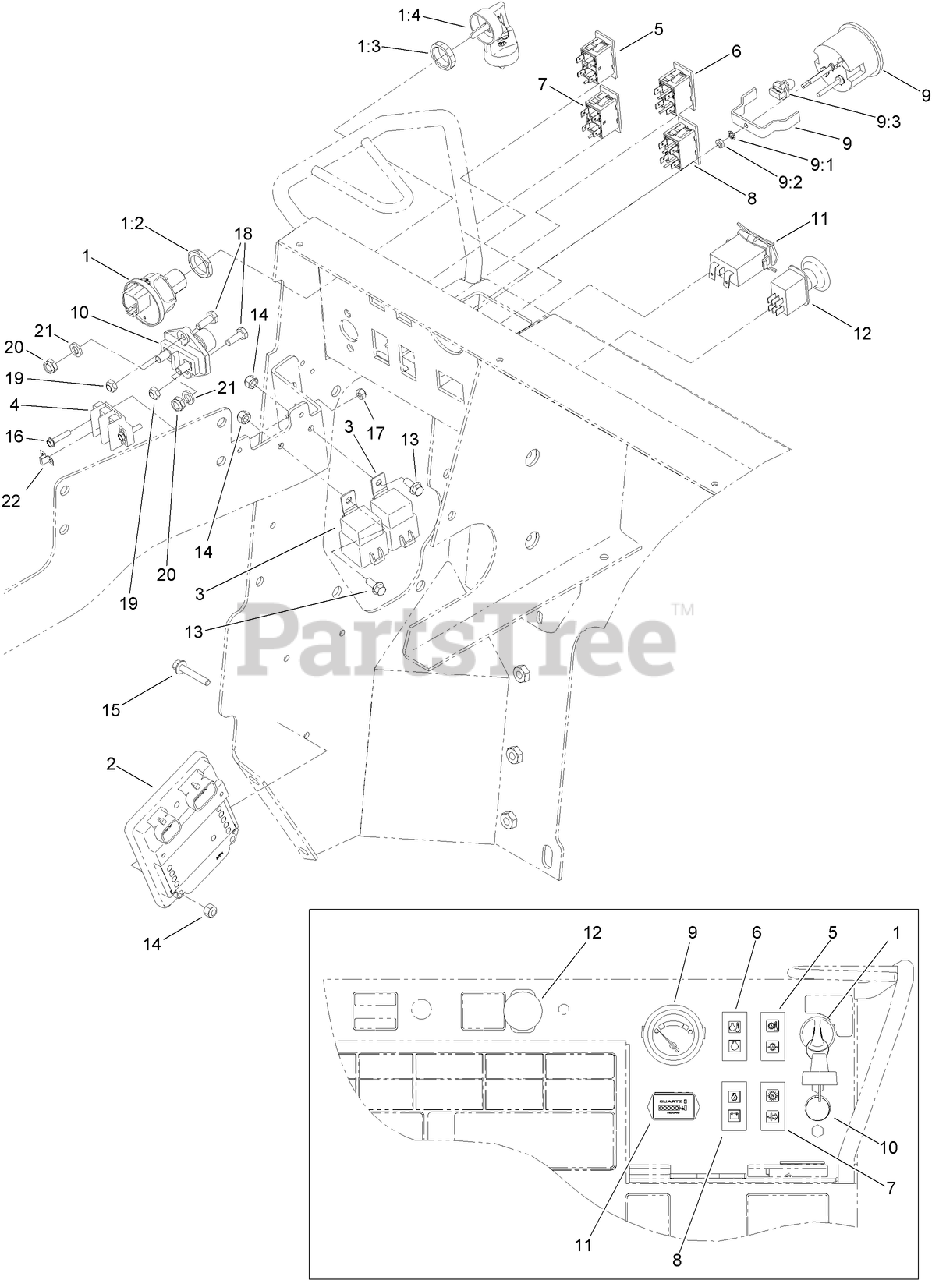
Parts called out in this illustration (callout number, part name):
1	IGNITION SWITCH ASM
1:2	NUT-HEX
1:3	NUT-FACE
1:4	IGNITION KEY SET
2	MODULE-CONTROL, STANDARD
3	RELAY
4	BLOCK-TERMINAL, GROUND
5	LAMP-WARNING
6	LAMP-WARNING
7	LAMP-WARNING
8	LAMP-WARNING
9	GAUGE-FUEL
9:1	WASHER-LOCK, INT
9:2	NUT-HEX
9:3	Bulb And Lamp ASM
10	SWITCH-STARTER
11	METER-HOUR
12	SWITCH-PTO,ON-ON-NONE
13	SCREW-HHF
14	NUT-LOCK, NI
15	SCREW-HHF
16	SCREW-HWH
17	NUT-LOCK, NI
18	SCREW-HH
19	NUT-LOCK, CONE
20	NUT-LOCK, NI
21	WASHER-LOCK
22	STRIP-JUMPER
